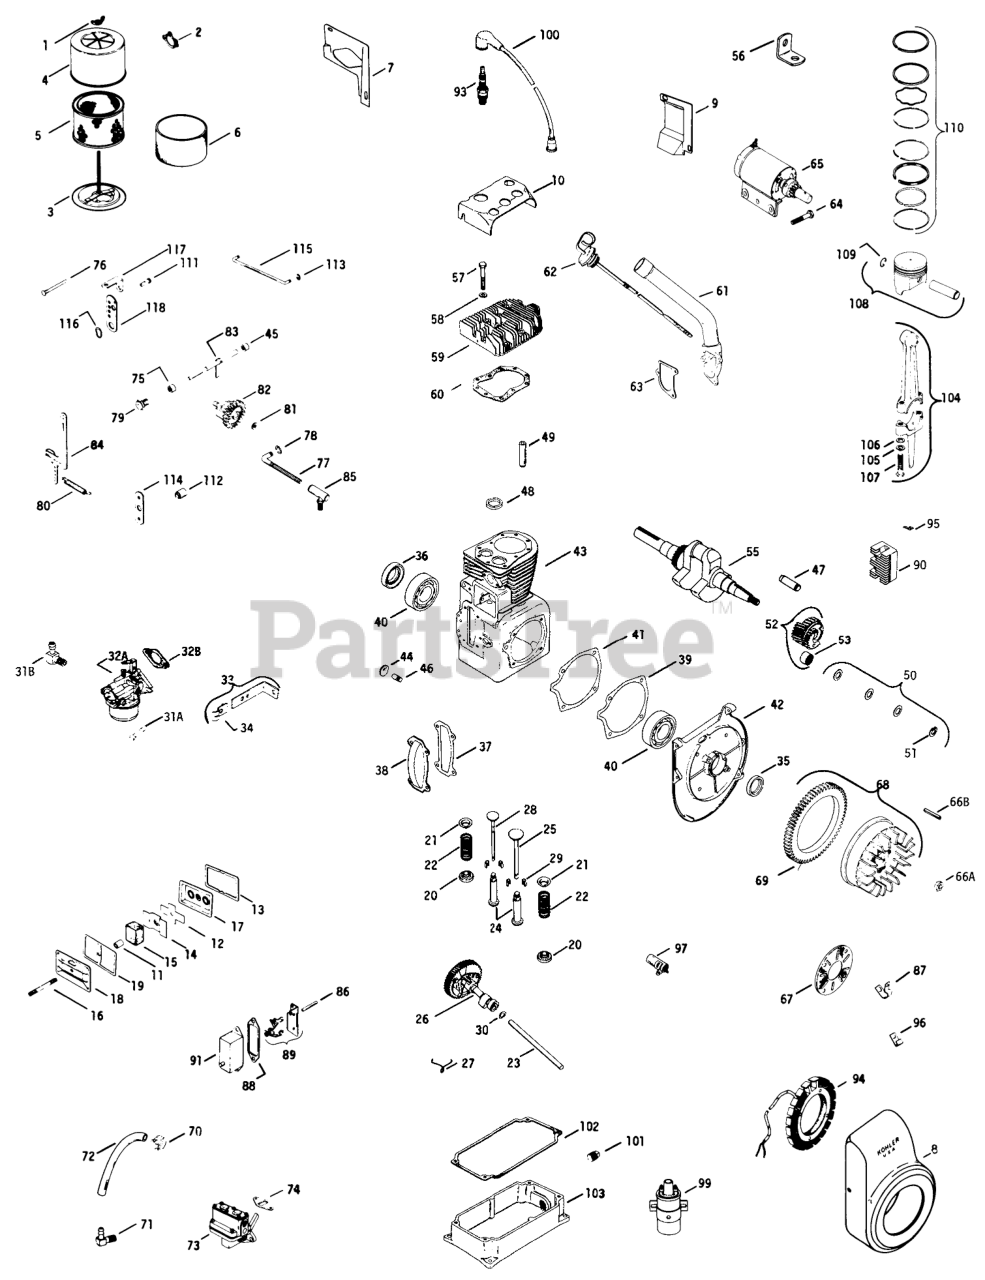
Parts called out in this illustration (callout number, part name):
1	Nut-Wing
2	Gasket-Air Horn
3	Base-Air Cleaner
4	Cover-Air Cleaner
5	Element
6	Element
7	BaffLe side air
8	Housing-Blower
9	Baffle, cylinder
10	Baffle, head
11	Seal
12	Reed
13	Gasket
14	Baffle breather
15	Filter Breather
16	Stud, valve cover
17	Plate
18	Cover valve
19	Gasket
20	Rotator
21	Retainer-Spring
22	Spring
23	Pin (Service)
24	Tappet
25	Valve-Intake
26	Camshaft-assembly
27	Spring-Actuating
28	Valve exhaust
29	Keeper, Valve
30	Spacer
31A	Screw sitd. hd.
31B	Elbow
32A	Carburetor-assembly
32A	Repairkit
32B	Gasket
33	Bracket, choke
34	Clip
35	Seal, Front OiI
36	Seal rear oil
37	Gasket
38	Cover
39	Gasket
40	Ball Bearing
41	Gasket
42	Plate Bearing
43	Block cylinder-assembly (Use 45_782_02 Miniblock)
44	Plug
45	Bearing
46	Shaft-Govemor
47	Shaft
48	Insert
49	Guide Valve
50	Kit-Spacer
51	Retainer
52	Gear
53	Bearing,needle
55	Crankshaft
56	Lift Cable
57	Screw
57	Screw-H.C.
58	Washer
59	Head, cylinder
60	Gasket, head
61	Tube, fill
62	Dipstick
63	Gasket
64	Screw
65	Starter-assembly
65	Kit, Brush & Spring
66A	Nut
66B	Key
67	Screen grass
68	Flywheel-assembly
69	Gear Ring
70	Clamp
71	Elbow
72	Line Fuel
73	Pump, fuel
74	Gasket, pump
75	Spacer
76	Pin-GovemorStop
77	Rod ball joint
78	Retainer Rod
79	Bushing
80	Spring-Governor
81	Washer
82	Gear, Governor
83	Shaft, Governor
84	Lever, Governor
85	Ball Joint
86	Rod, breaker
87	Clip
88	Gasket, Cover
89	Breaker
90	Regulator
91	Cover breaker
93	Plug, spark
94	Stator
95	Connector
96	Clip
97	Condenser
99	Coil
100	Kit, Hi-Tension
101	Plug
102	Gasket
103	Base, oil pan
104	Rod, conn.-assembly Std.
104	Rod conn.-assem. (.010 U.S.)
105	Washer
106	Washer
107	Screw, connecting rod
108	Piston-assembly (Std.)(Includes pin & retainers)
108	Piston-assembly (.003)(Includes pin & retainers)
108	Piston-assembly (.010)(Includes pin & retainers)
108	Piston-assembly (.020)(Includes pin & retainers)
108	Piston-assembly (.030)(Includes pin & retainers)
109	Pin, Retainer
110	Ring set-Std. & .003
110	Ring set-.010
110	Ring set-.020
110	Ring set-.030
111	Clamp, swivel wire
112	Spacer
113	Retainer Rod
114	Bellcrank
115	Rod, throttle
116	Washer
117	Spacer
118	Bracket
118	Gasket Set
118	Miniblock
118	Shortblock
118	Service Engine
